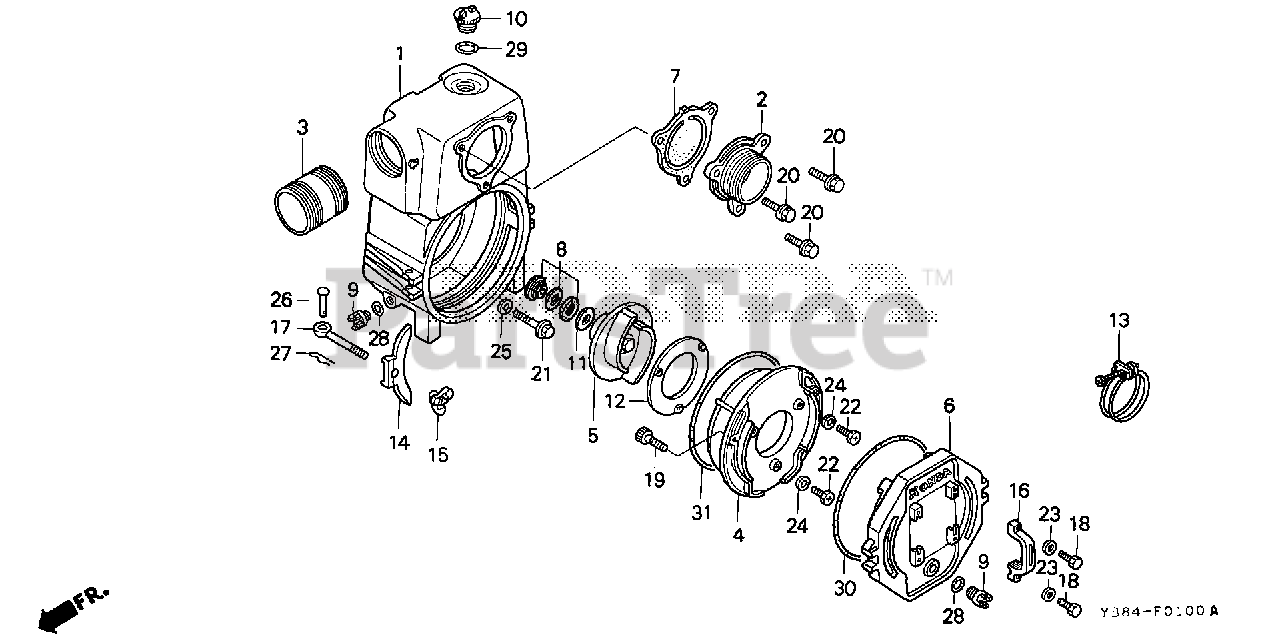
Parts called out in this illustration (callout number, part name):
4	CASE, VOLUTE
6	COVER, DRAIN
7	VALVE, CHECK
8	SEAL ASSY., MECHANICAL
9	CAP, DRAIN
10	CAP, FILLER
11	SHIM, ADJUSTING
13	BAND, HOSE
14	HOLDER, DRAIN COVER
15	KNOB, DRAIN COVER
16	HANDLE, DRAIN COVER
17	BOLT, DRAIN COVER
18	BOLT, HANDLE SETTING
19	BOLT, SOCKET (8X20)
20	BOLT-WASHER (10X30)
21	BOLT, FLANGE (8X50)
22	BOLT (6X16)
23	WASHER, PLAIN (6MM)
24	WASHER, SPRING (6MM)
25	GASKET, SEAL
26	PIN, HINGE
28	O-RING (3.5X23.7)
29	O-RING (3.5X29.7)
30	O-RING (5.7X239.3)
31	O-RING (3.53X215.49)
